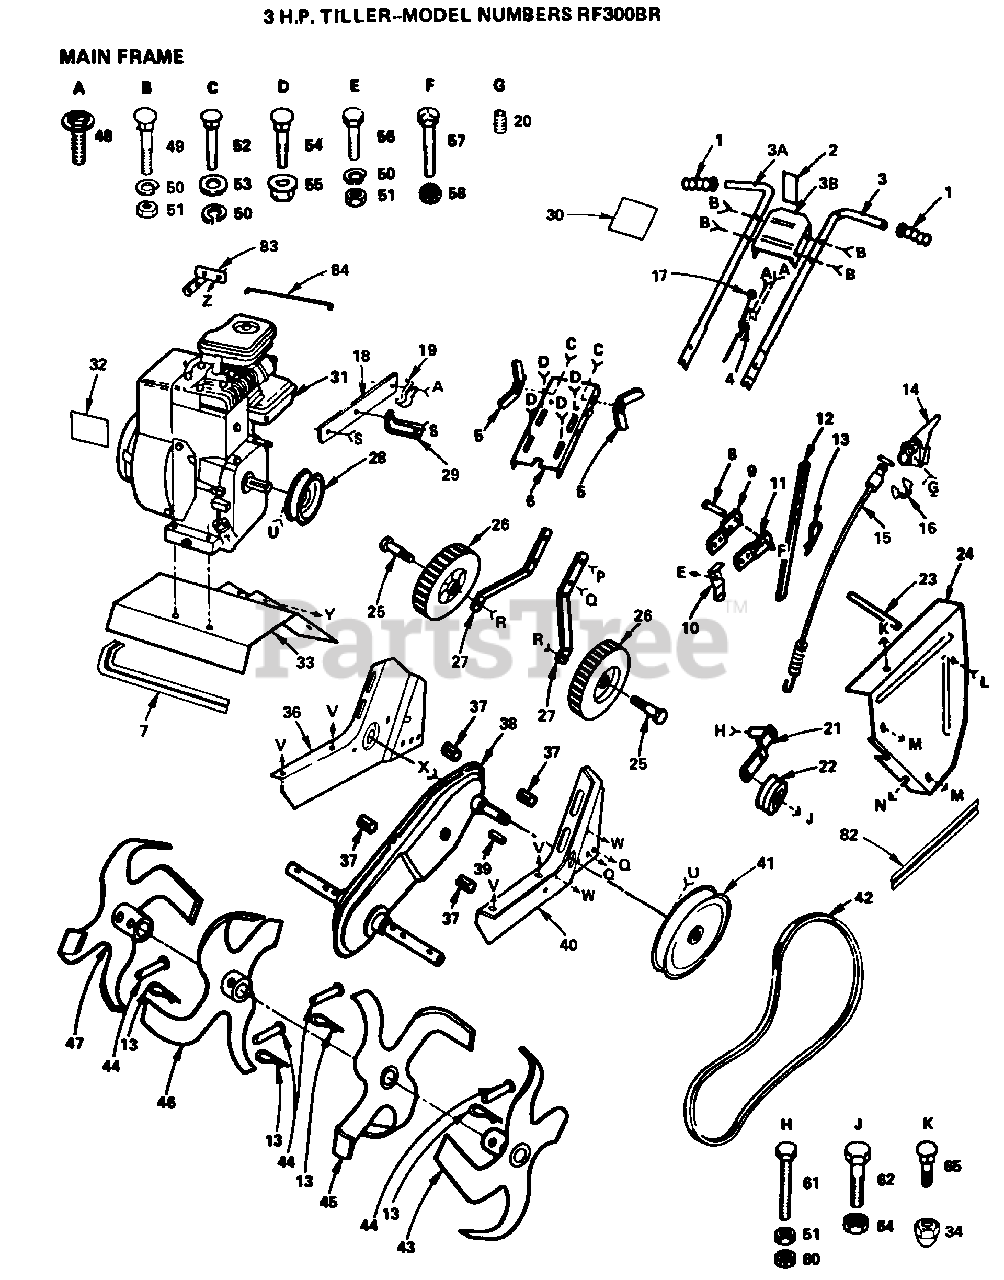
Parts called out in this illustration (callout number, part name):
2	DECAL - THROTTLE
3B	BRACKET - HANDLE
4	THROTTLE CONT TI
7	DECAL - TINE SHIELD
8	DRILLED RIVET RT
9	STAKE.SUPT.TILLER
10	STAKE SPRING CT
13	SPRING.RETAINER
14	CONTROL LEVER TI
15	CABLE CLUTCH T
16	KLIP RING
18	BRACKET-GUARD TI
19	CONDIUT CLIP T
20	SCREW
21	IDLER ARM TI
23	SPLIT SPACER
25	BOLT M
31	ENGINE, B&S
33	SHIELD - TINE
34	NUT-CAP TI
37	SPLIT SPACER RT
39	KEY T
41	TRANS SHEAVE RT
44	DRILLED RIVET RT
48	SCREW TI
50	LOCKWASHER
51	NUT.HEX.5/16-18
52	BOLT
53	WASHER
55	NUT
56	BOLT
58	GRIPCO NUT
64	NUT
65	BOLT
82	DECAL - BELT GUARD
